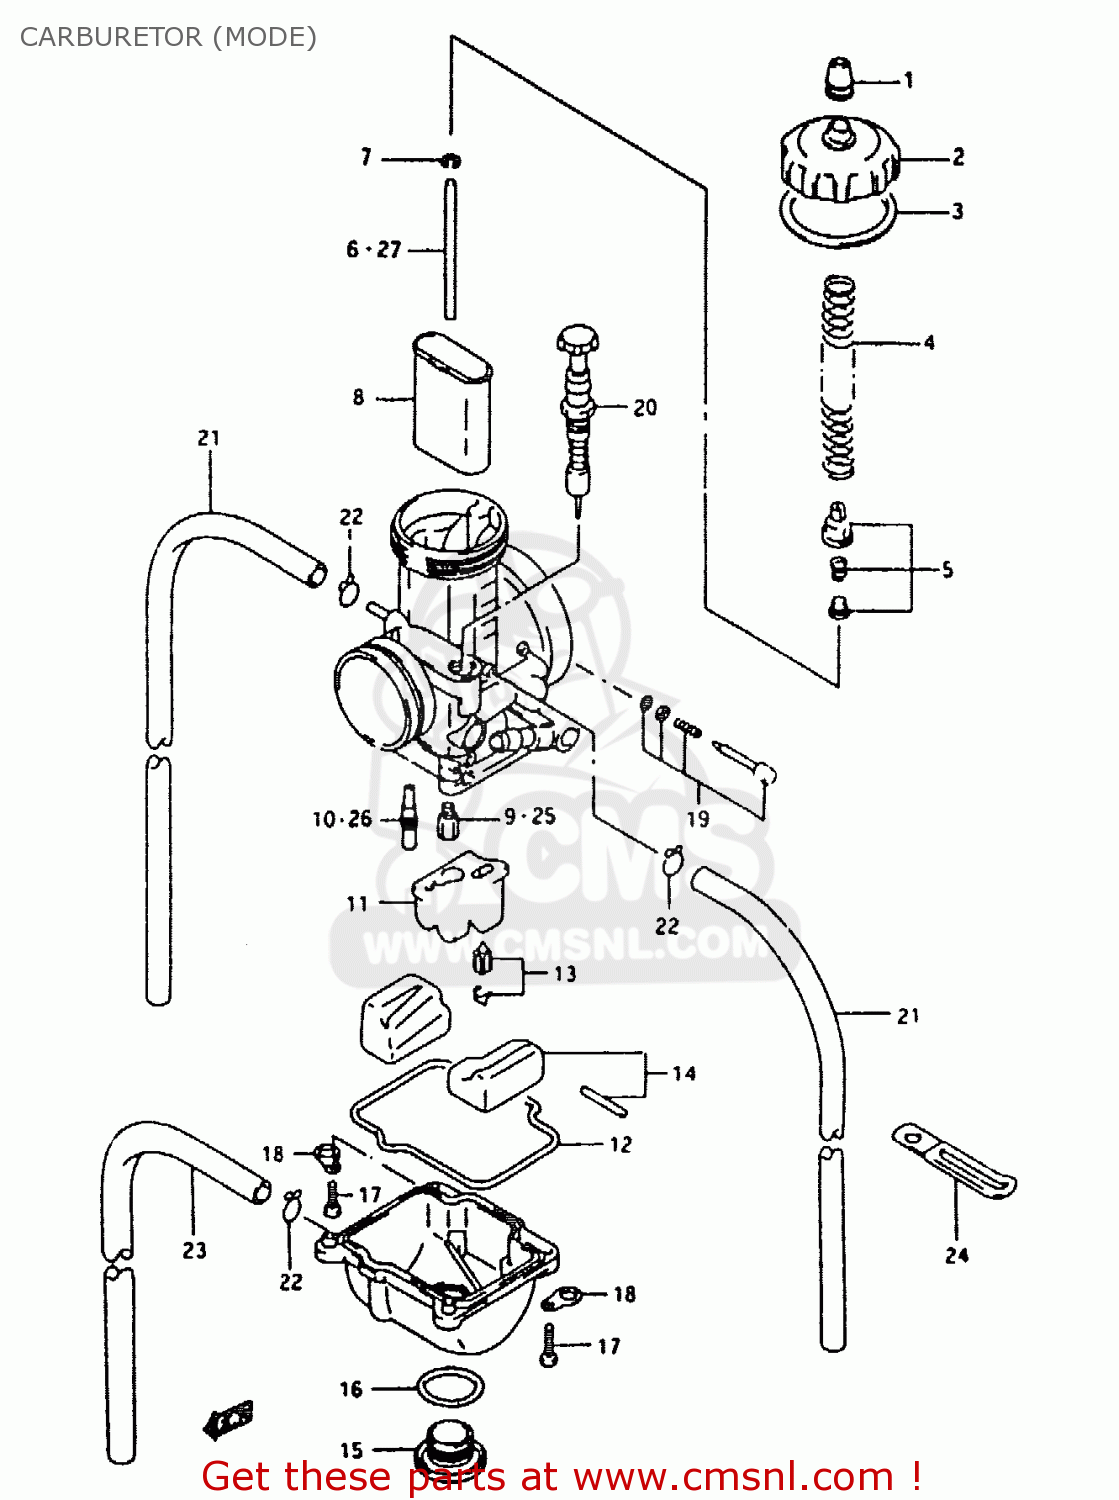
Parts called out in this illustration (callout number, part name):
1	CAP,CARBURETOR
2	CAP,TOP
3	GASKET,TOP CAP
4	SPRING
5	HOLDER SET,CABLE
6	NEEDLE,JET(R1472M 1L)
7	CLIP,NEEDLE
8	VALVE,PISTON(CA:5.0)
9	JET,MAIN(180)
10	JET,SLOW(60)
11	HOLDER
12	GASKET,FLOAT CHAMBER
13	VALVE SET,FLOAT
14	FLOAT SET
15	BOLT,DRAIN
16	O RING
17	SCREW
18	PLATE
19	SCREW SET,AIR
20	PLUNGER ASSY
21	HOSE (4X7X440)
22	CLIP
23	HOSE(3.5X6.5X600)
24	CLAMP(L:45)
25	JET,MAIN(145)
26	JET,SLOW(50)
27	NEEDLE SET,JET
